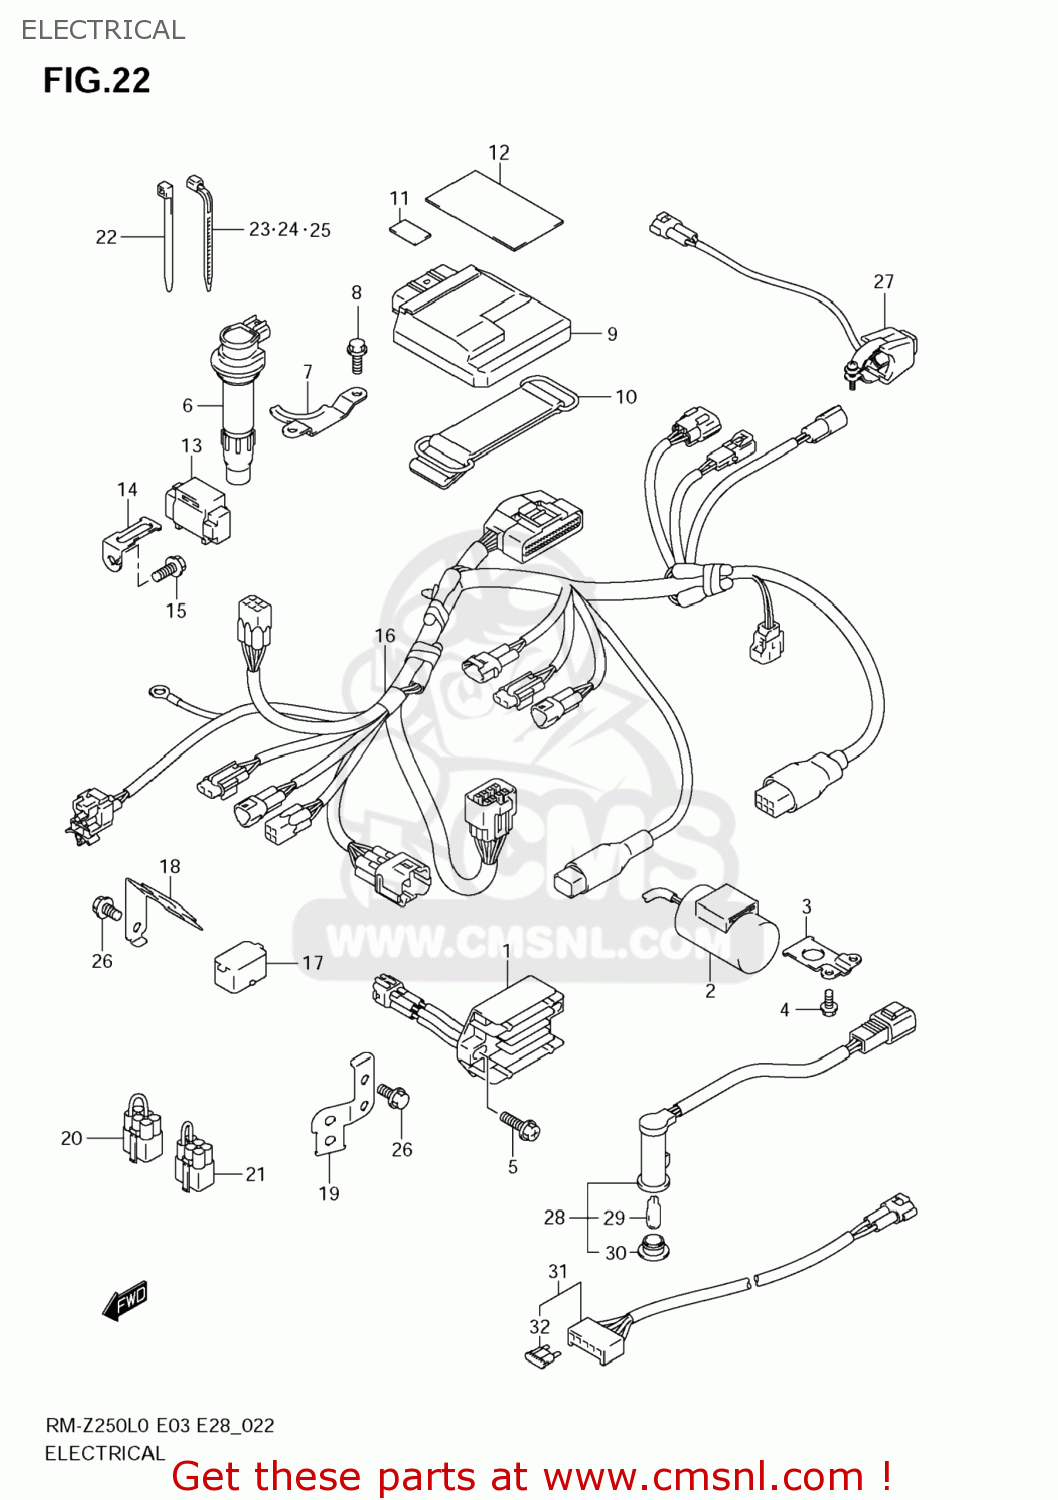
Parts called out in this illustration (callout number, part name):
1	RECTIFIER ASSY
2	CONDENSER ASSY
3	BRACKET,CONDENSER
4	BOLT(6X10)
5	SCREW
6	COIL ASSY,IGNITION
7	RETAINER,IGNITION COIL
8	BOLT
9	CONTROL UNIT,FI
10	BAND,CDI UNIT(L:80)
11	CUSHION(30X50X3)
12	PROTECTOR(170X95X3.0)
13	SENSOR ASSY,FUEL CUT
14	BRACKET,FUEL CUT SENSOR
15	SCREW
16	HARNESS,WIRING
17	CAP,TS
18	BRACKET,COUPLER
19	BRACKET,COUPLER
20	WIRE,SHORT
21	WIRE,SHORT
22	CLAMP(L:95)
23	CLAMP(L:95)
24	CLAMP(L:125)
25	CLAMP(L:165)
26	BOLT
27	SWITCH ASSY,ENGINE STOP
28	LAMP ASSY,FI INDICATOR
29	BULB(12V3.4W,T10)
30	LENS(RED)
31	WIRE,BATTERY
32	FUSE(10A)
